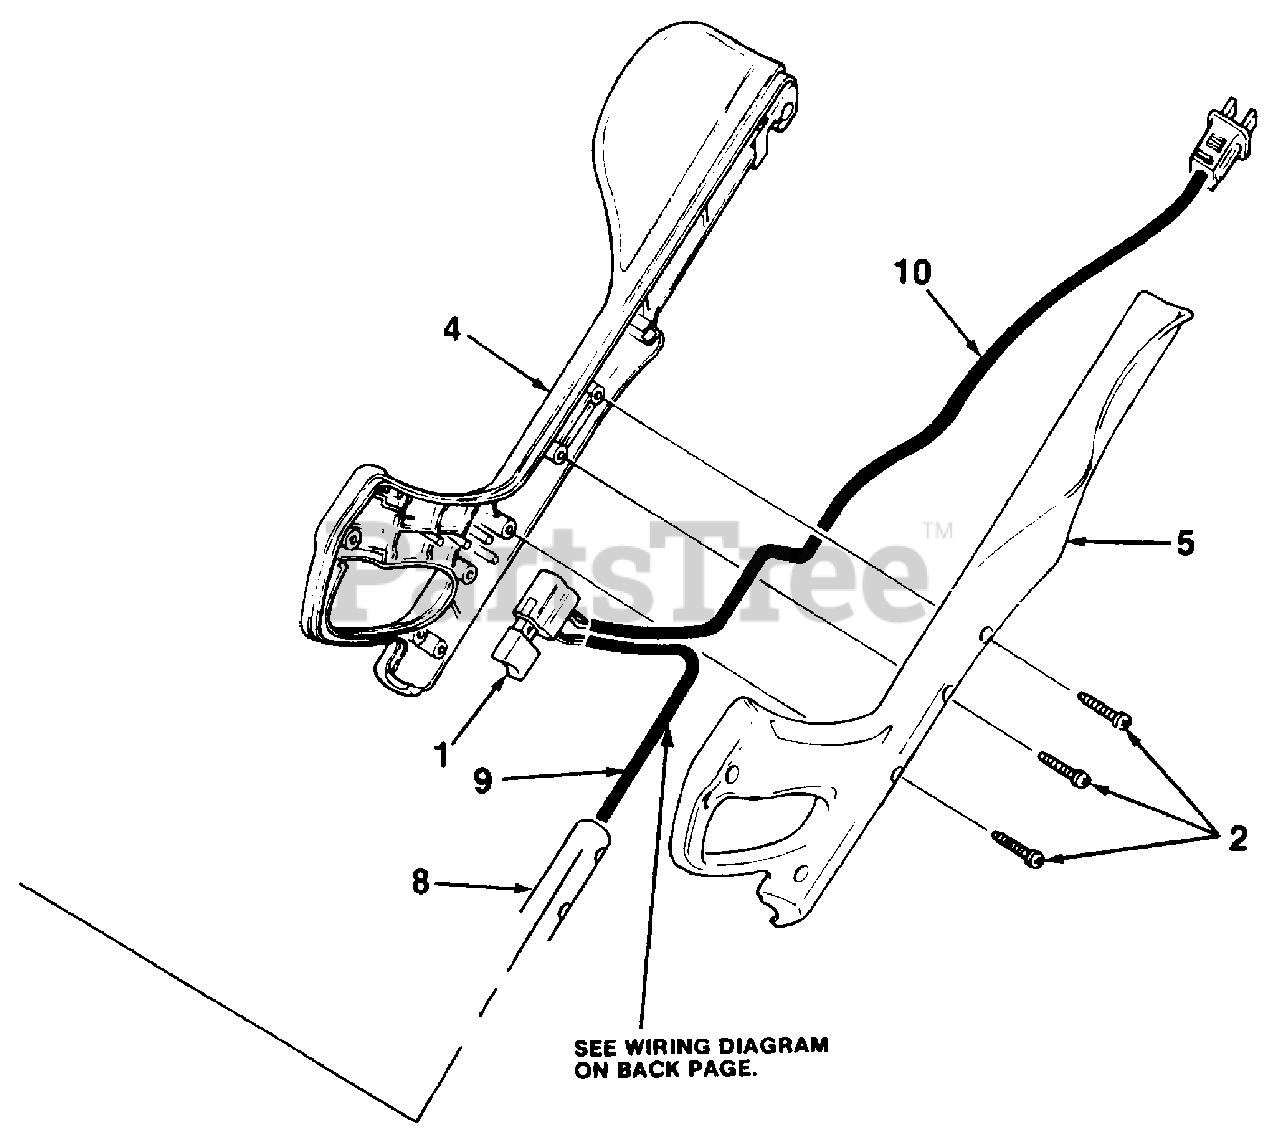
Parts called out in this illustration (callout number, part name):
2	SCREW- Thread forming 10-16 x 9/16
4	HANDLE- Right side
5	HANDLE- Left side
9	CABLE- Electrical
10	CORD SET
